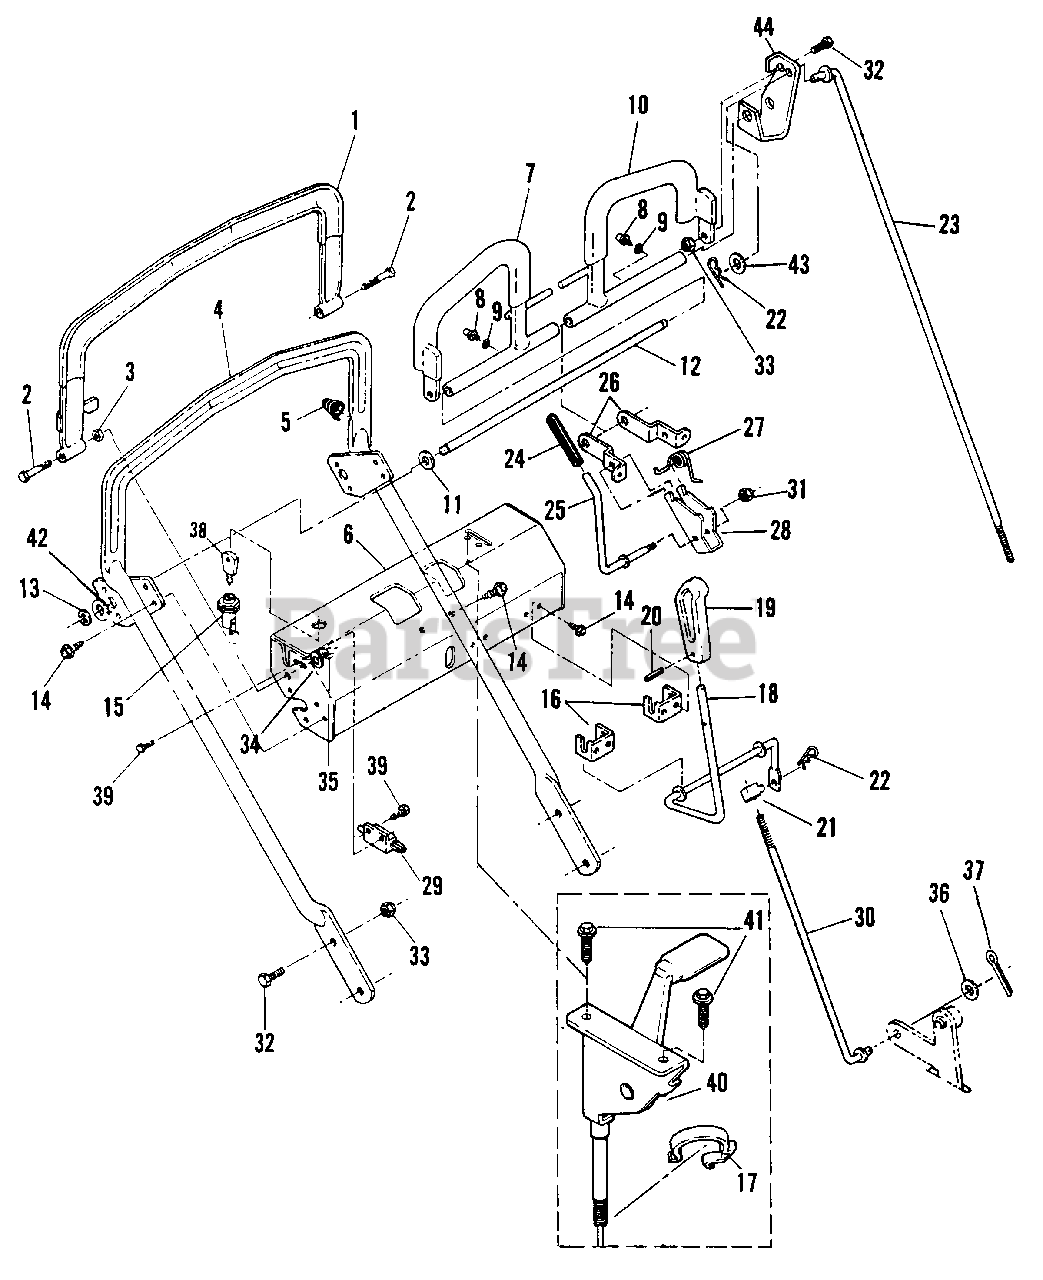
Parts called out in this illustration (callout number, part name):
1	OPC BAIL (W/Grip)
2	BOLT, 1/4" - 20 x 1 3/4" Lg. Hex
3	NUT, 1/4" - 20 Hex J
4	HANDLE, Loop
5	SPRING, Conical
6	CONSOLE, Control
7	TRACTION LEVER, R.H.
8	GREASE FITTING, 1/4" - 28 Str. Zerk
9	LOCKWASHER, 1/4" Int. Tooth
10	TRACTION LEVER, L.H.
11	WASHER, 1/2" Flat
12	ROD, Pivot
13	E-RING, 1/2"
14	SCREW, 1/4" - 20 x 1/2" Lg. Hex. Wshr. Self-Tap (Black)
15	SWITCH, "ON-OFF"
16	BRACKET, Lever Mounting
17	CLIP, Cable
18	LEVER, Blade Engagement
19	KNOB
20	PIN, 3/16" x 3/4" Lg. Roll
21	SWIVEL
22	PIN, #13 Hair
23	ROD, Traction
24	GRIP, Neutral Latch
25	LEVER, Neutral Latch
26	BRACKET, Neutral Mounting
27	SPRING, Neutral
28	LATCH
29	SWITCH (OPC)
30	ROD, Blade Clutch (Loop Handle)
31	LOCKNUT, 1/4" Nyloc
32	BOLT, 3/8" x 1" Lg. Hex., Gr. 5
33	NUT, 3/8" Nyloc
34	WASHER, 1/4" Flat
35	NUT, 1/4" - 20 Nyloc
36	WASHER, 3/8" Flat
37	PIN, 3/32" x 1" Cotter
38	KEY, Switch (With Cover)
39	SCREW, #12-14 x 1/2" Hex Flange Self-tap
40	CONTROL, Throttle
41	SCREW, #10-24 x 1/2" Hex Washer Self-Tap (Torx)
42	BUSHING, 1/2" Machine
43	SPACER
44	BRACE, Handle - LH
